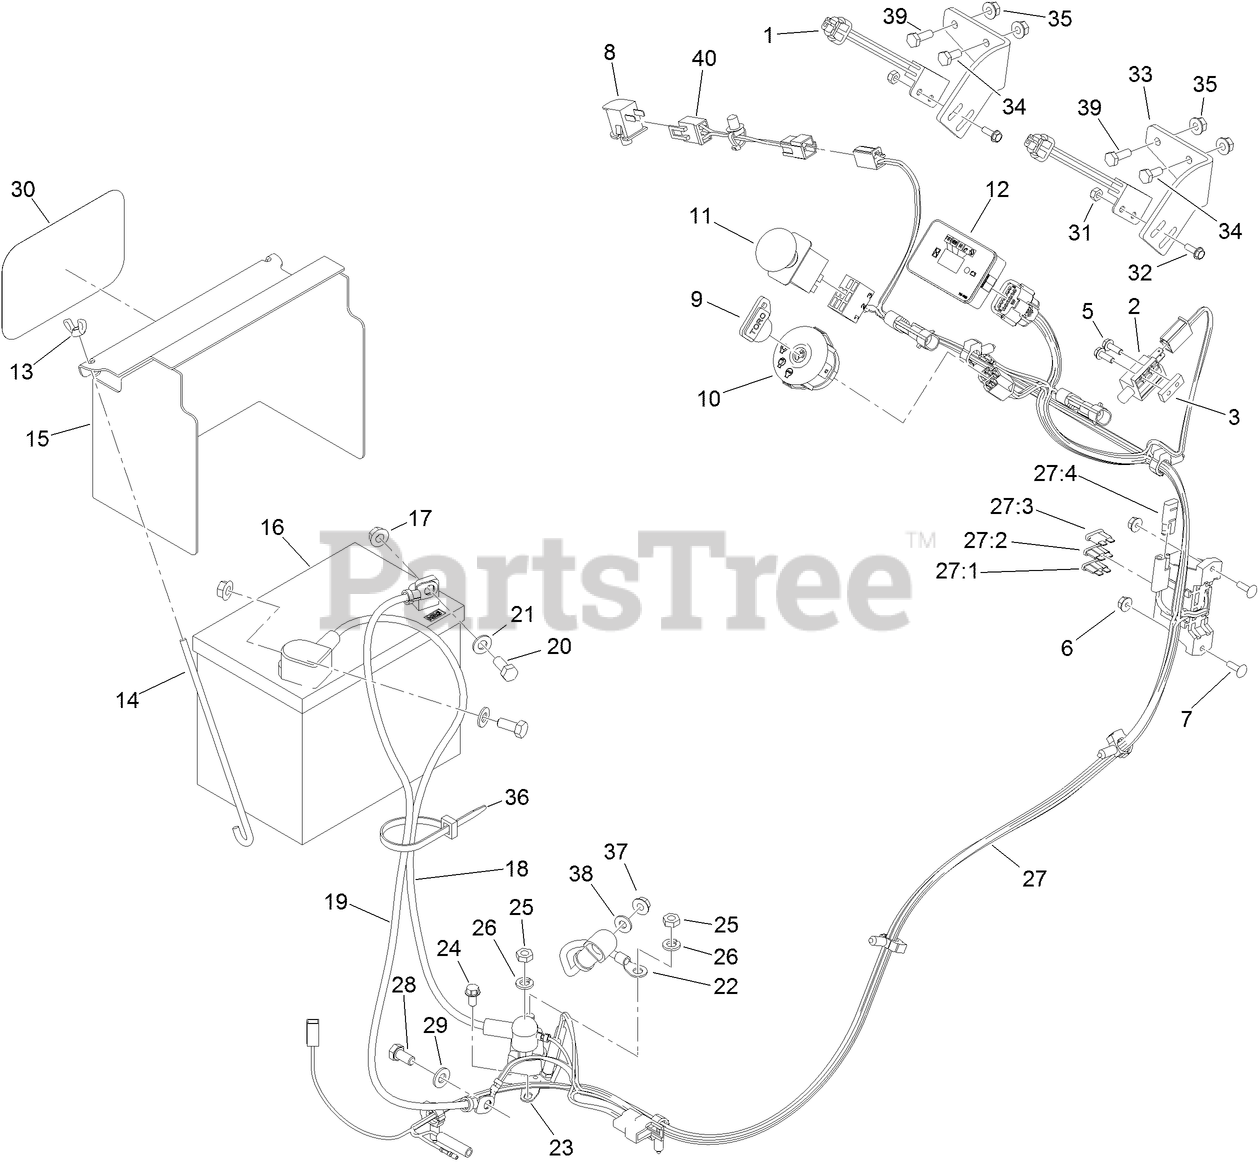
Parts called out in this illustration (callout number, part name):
1	SWITCH-PROXIMITY
2	SWITCH-CLOSED, NORMALLY
3	PLATE-TAPPED
5	SCREW-SHWH
6	NUT-LOCK, FLANGE
7	BOLT-CARR
8	SWITCH-BAIL
9	KEY-IGNITION
10	SWITCH-IGNITION
11	SWITCH-PTO, ON-ON-(ON)
12	MODULE-HOUR METER
13	WINGNUT
14	BOLT-HOLDDOWN
15	COVER-BATTERY
16	BATTERY-DRY
17	NUT-HHF, SMOOTH
18	CABLE-BATTERY, POSITIVE
19	CABLE-GROUND, NEGATIVE
20	SCREW-HH
21	WASHER-PLAIN
22	CABLE-BATTERY, RED
23	SOLENOID
24	SCREW-HWH
25	NUT-JAM
26	WASHER-LOCK
27	HARNESS-WIRE
27:1	FUSE-BLADE, 30 AMP
27:2	FUSE-BLADE, 25 AMP
27:3	FUSE-BLADE, 10 AMP
27:4	CAP-PLUG
28	SCREW-HH
29	WASHER-PLAIN
30	DECAL
31	NUT-LOCK, NI
33	BRACKET-MOUNT, SWITCH
34	SCREW-HH
35	NUT-HHF
36	TIE-CABLE
37	NUT-HF
38	WASHER-FLAT
39	SCREW-HH
40	HARNESS-WIRE, JUMPER (OPC)
